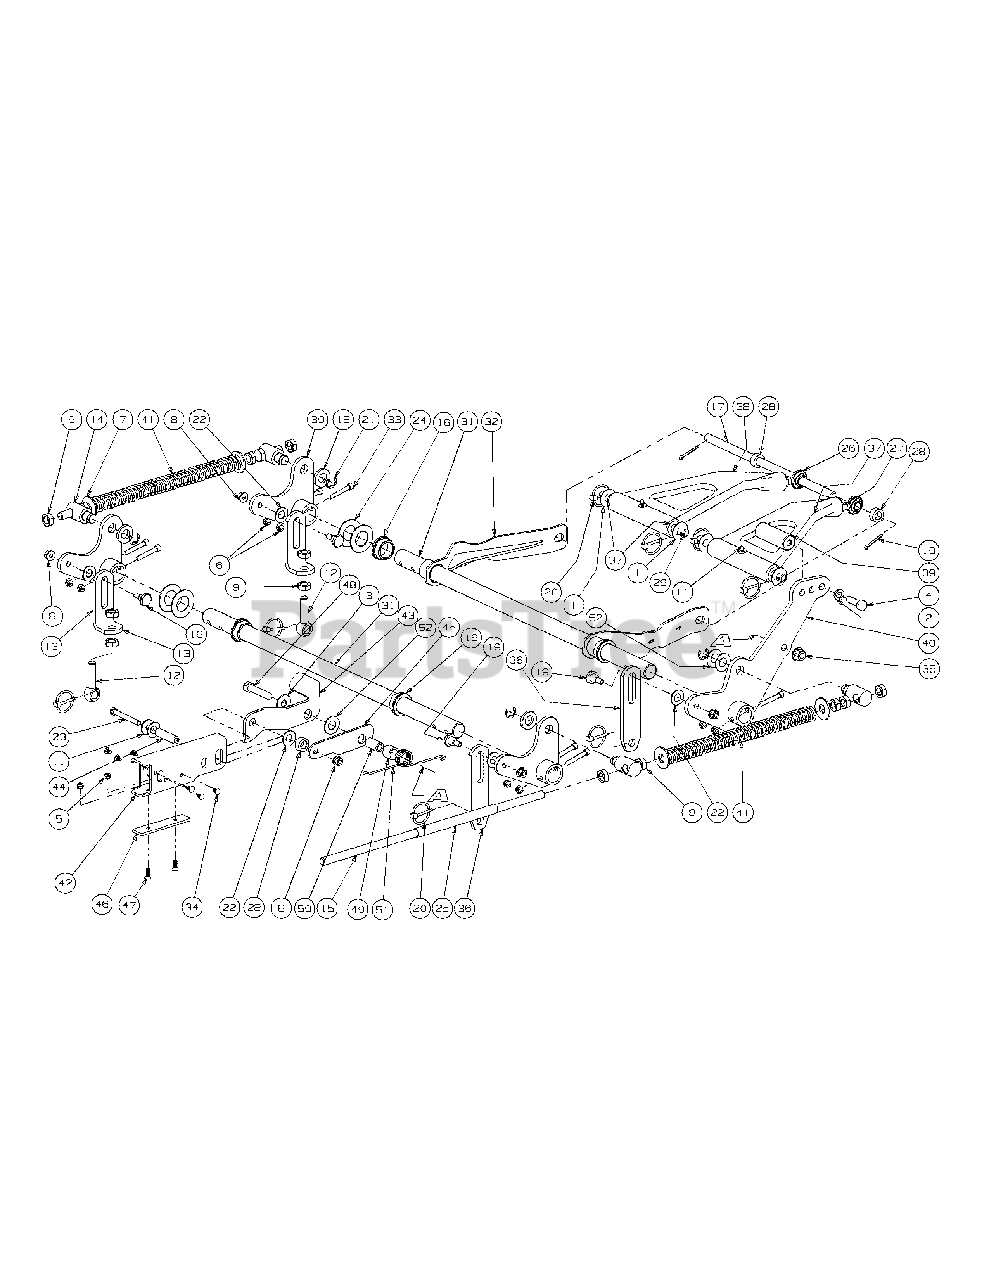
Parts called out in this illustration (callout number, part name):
1	Washer, 1.5 x .655 x .055
2	Lock Washer, 1/2
3	Flat Washer, 1/2
4	Hex Cap Screw, 1/2-13 x 1.50
5	Lock Nut w/Nylon Insert
6	Nut, 5/16-18, Nylock
7	Flat Washer, 5/8
8	Hex Nut, Flange Lock, 3/8-16
9	Jam Nut, 5/8-11
10	Cotter Pin, 3/16 x 1-1
11	Flat Washer, 1.25 x .411 x .100
12	Eye Bolt, 5/8ID
13	Eye Bolt Mount Link, 5/8 ID
14	Ferule Lift
15	Lift Connector Rod
16	Hex Flange Bearing, 1.25 ID
17	Front Lift Link, Rod Mount
18	Spacer, .812 ID x .268 Lg.
19	Shoulder Screw, 0.625 OD x .437 Lg.
20	Linch Pin, 3/16 Dia.
21	E Clip, 3/4 Dia.
22	Nylon Flat Washer, 5/8
23	HHCS, 3/8-16, 3.00
24	Flat Washer, 1.25 ID
25	Hose, 5/8 ID 13/16 OD, 8" LG
26	Rod End, Male
27	Jam Nut, 5/8-18
28	Spacer, .630 ID x 1.06 OD x .440
29	Deck Lift Link Rod
30	Bellecrank Weldment Assembly
31	Deck Lift Shaft
32	Front Frame Strut Assembly
33	Socket Head CapScrew, 5/16-18 x 2
34	Rivet, 1/4 x 5/8
35	Nut, 1/2-13, FlangeLock
37	Bearing Lift Brace Assembly, Left Hand
38	Bearing Lift Brace Assembly, Right Hand
39	Deck Lift Foot Pedal
40	Deck Lift Foot Pedal Weldment
41	Lift Compression Spring
42	Lift Tube, 3.0 x 1.5
43	Lift Link Bracket
44	Spacer, .375 ID x .625 OD x 1.53
45	Yoke Plate
46	Lift Wear Plate
47	Flat Head Cap Screw, 1/4-20 x .75
48	HHCS, 1/2-13 x 2.50
49	Spacer, .76 ID x 1.0 OD x .75
50	Spacer, .50 ID x .75 OD x 1.313
51	Torsion Spring, .120 Wire x 1.32 OD
52	Washer, .76 x 1.49 x .06
